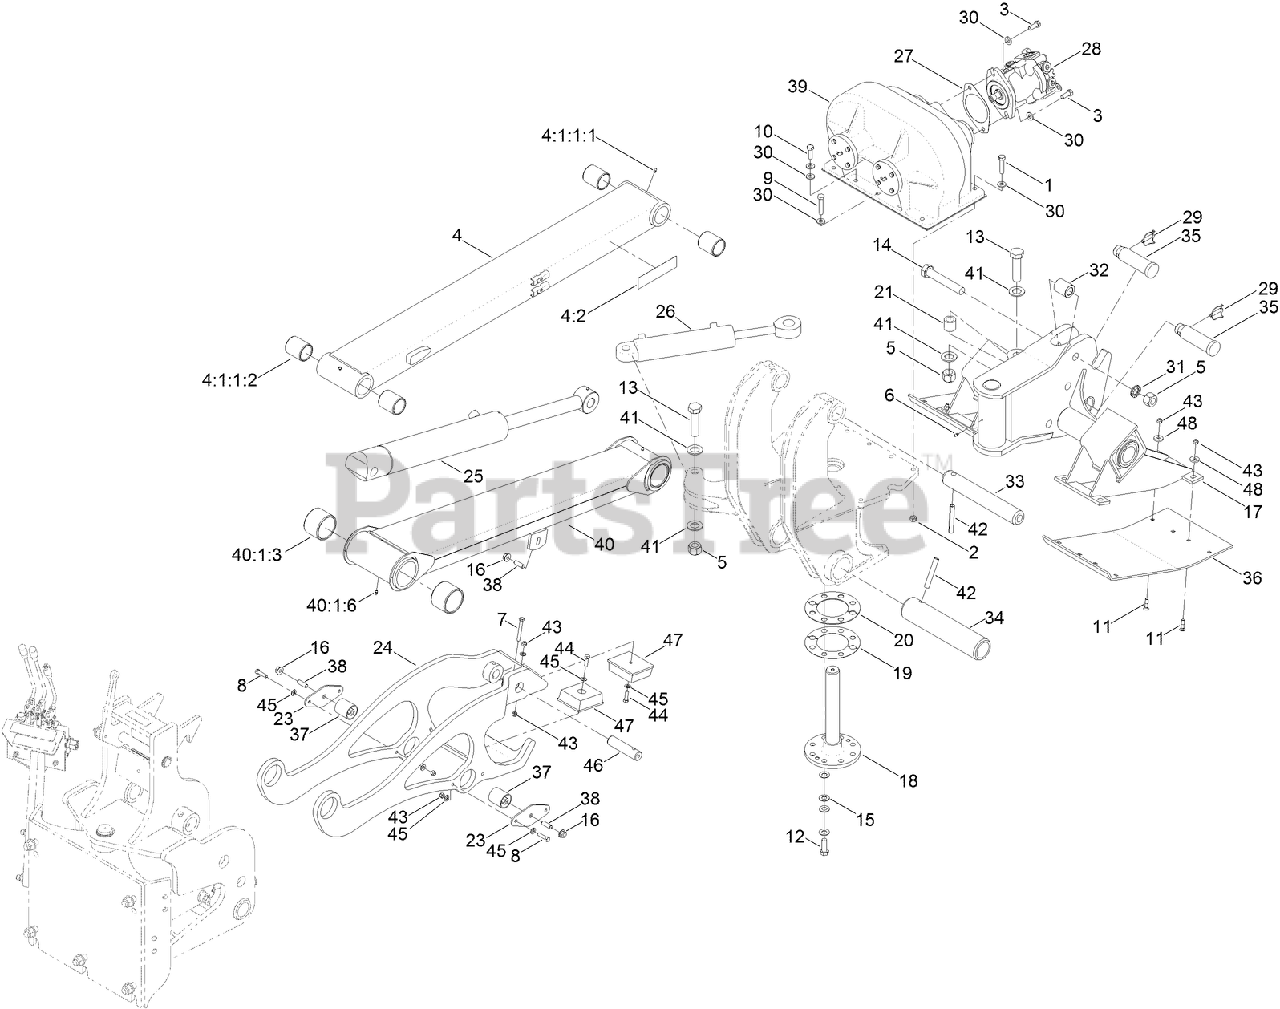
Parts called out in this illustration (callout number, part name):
1	SCREW-HH
2	LOCKNUT
3	SCREW-HH
4	ARM-PLOW, UPPER W/DECALS
4:1	ARM-PLOW, UPPER
4:1:1:1	FITTING-GREASE
4:1:1:2	BUSHING-ARM, PLOW
4:2	DECAL-DANGER, PLOW
6	FITTING-GREASE
7	SCREW-HH
8	SCREW-HH
9	SCREW-HH
10	SCREW-HH
11	SCREW-PLOW
12	SCREW-HH
13	BOLT-HH
14	BOLT-HH
15	WASHER-FLAT
16	NUT-HHF
17	MOUNT-BLADE
18	AXLE-PIVOT, BLADE MOUNTING
19	SHIM-PLOW PIVOT
20	SHIM-PLOW PIVOT (THICK)
21	TUBE-ROD END SPACER
23	PLATE-ISOLATOR MOUNTING
24	CRADLE-PLOW LIFT
25	CYLINDER-PLOW LIFT
26	CYLINDER-BLADE
27	GASKET-HYD PUMP
28	HYD MOTOR ASM
29	PIN-KLIK
31	WASHER-LOCK
32	TUBE-SPACER, SOD CUTTER
33	PIN-PLOW ARM, UPPER
34	PIN-PLOW ARM, LOWER REAR
35	PIN-MOUNTING, BLADE
36	PLATE-SHOE WEAR
37	MOUNT-ISOLATOR
39	BOX-SHAKER
40	ARM-PLOW, LOWER
40:1	ARM-PLOW, LOWER
40:1:3	BUSHING
40:1:6	FITTING-GREASE
42	PIN-SPIRAL
43	NUT-HEX
44	SCREW-HH
45	WASHER-FLAT
46	PIN-ROD
47	BUMPER
48	WASHER
